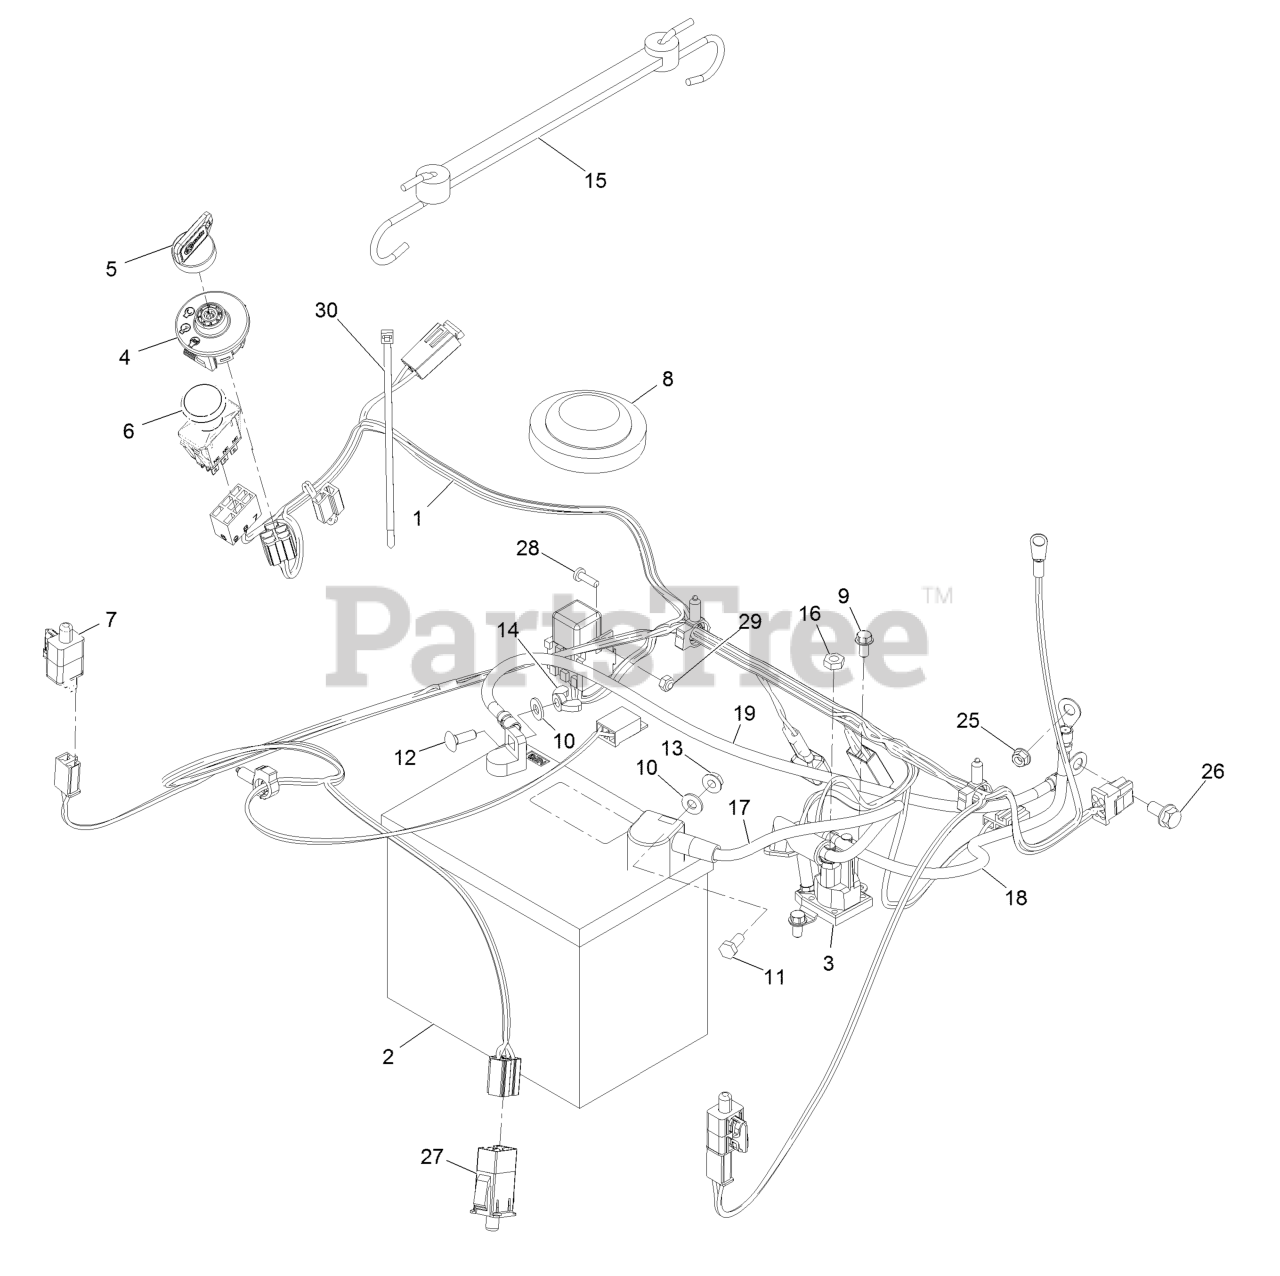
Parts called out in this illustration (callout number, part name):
1	Harness-Wire
2	Battery
3	Solenoid
4	Switch-Ignition
5	Key-Exmark Logo
6	Switch-PTO
8	Switch-Seat
9	Screw-HWH 1/4-20 X 1/2 Taptite
10	Washer-1/4 SAE
11	Screw-HH 1/4-20 X 5/8
12	Bolt-Carriage 1/4-20 X 3/4
13	Nut-Whizlock 1/4-20
14	Nut-Wing
15	Holddown-Battery
16	Nut-Jam 5/16-24
17	Cable-Battery, Red
18	Cable-Battery, Positive
19	Cable-Battery, Black
25	Nut-Hex M6-1 Flg
26	Screw-HH Flg 5/16-18 X 5/8
27	Switch-Delta
28	Screw-PPH #10-24 X 5/8
29	Nut-Nyloc #10-24
30	Tie-Cable
